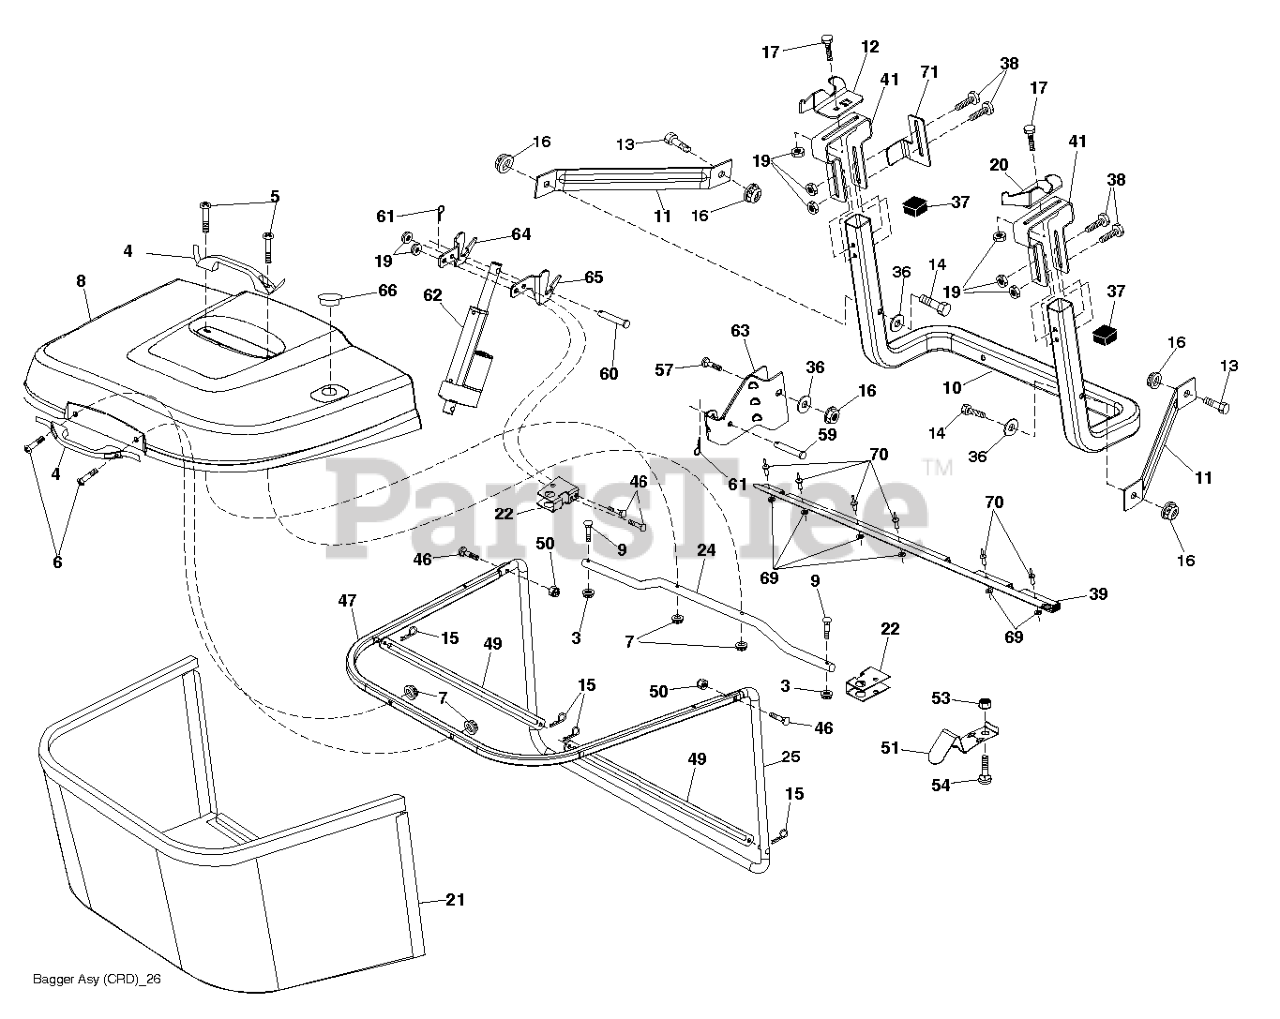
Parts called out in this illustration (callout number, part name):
3	NUT T
4	HANDLE.BAGGER.W/LVRS.BLK.CRD
5	SCREW.PAN.HEAD
6	REPL BY 532 75 00-29
8	COVER.BGR.CRD.WSLOTS.M
9	Bolt Carriage 1/4-20 x 2.25d x Gr.5
10	TUBE
11	BRACKET.SUPPORT.UPPER.BAG.CRD
12	BRKT PIVOT
14	BOLT-HEX EAK
15	RETAINER-SPRNG RB
16	NUT LOCK FLG 3/8-16 UNC
17	RP BOLT 5/16-18 X3/4 ZN/YEL GR
19	NUT LOCK HEX FLANGE 5/16-18
20	BRKT.PIVOT.RH.CRD
21	BAGGER.ASM.CRD.2007
22	BRACKET.BAGGER.SD.ELECTRIC.CRD
24	TUBE.PIVOT.BAG.CRD.BLACK
25	PIPE
36	WASHER
37	Plug Support Bagger CRD
38	BOLT.5/16-18X2.5
39	SEAL.BAGGER.CRD
41	BRACKET.BAGGER.SD.ELECTRIC.CRD
46	BOLT.CARRIAGE.5/16-18
47	PIPE
49	ROD
50	NUT.71038.31-18.HEX.NYLOCK
51	LATCH
53	NUT
54	BOLT
57	BOLT
61	RETAINER M
69	WASHER
70	RIVET RIVET POP
